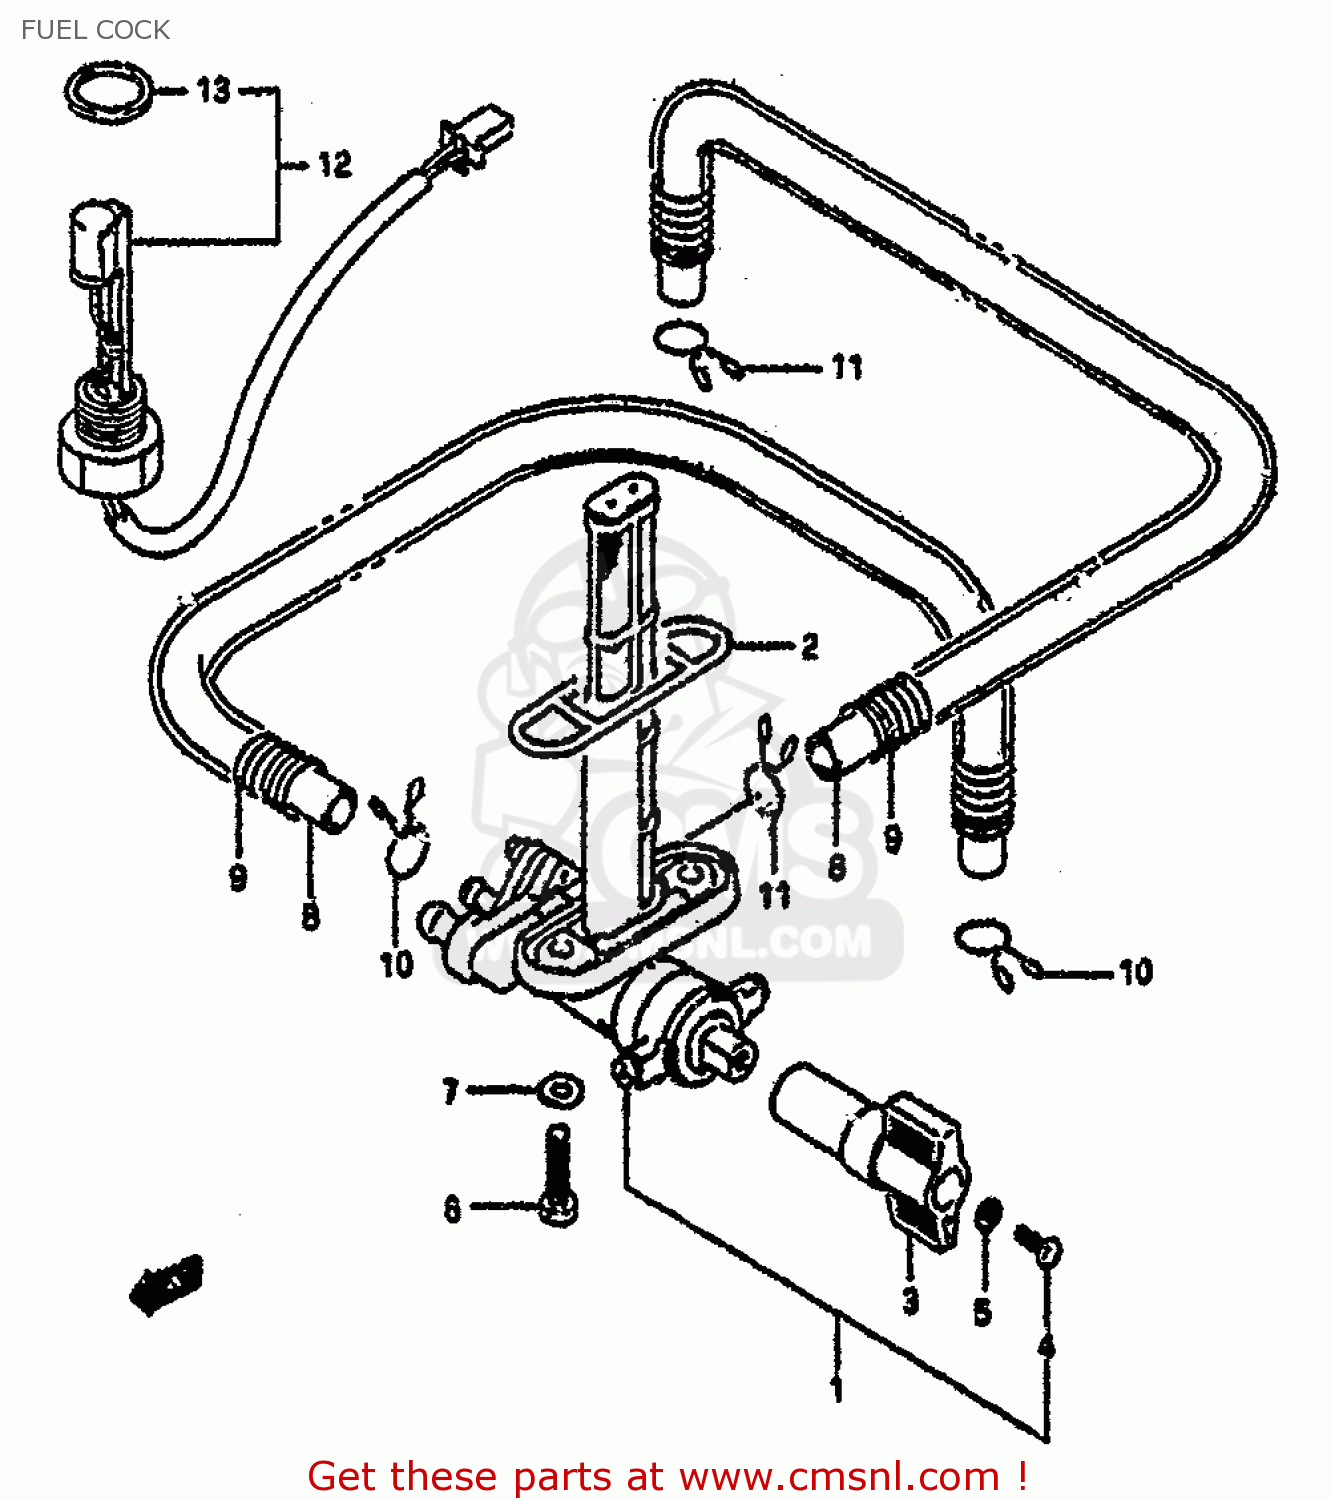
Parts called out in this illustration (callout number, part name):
1	COCK ASSEMBLY,FUEL
2	O RING,FUEL TANK JOINT
3	LEVER,FUEL COCK
4	SCREW
5	LOCK WASHER
6	BOLT(6X20)
7	GASKET(6.4X11.5X0.8) (NAS)
8	HOSE
9	SPRING
10	CLIP
11	CLIP
12	GAUGE ASSEMBLY,FUEL LEVEL
13	GASKET,FUEL LEVEL GAUGE (NAS)
